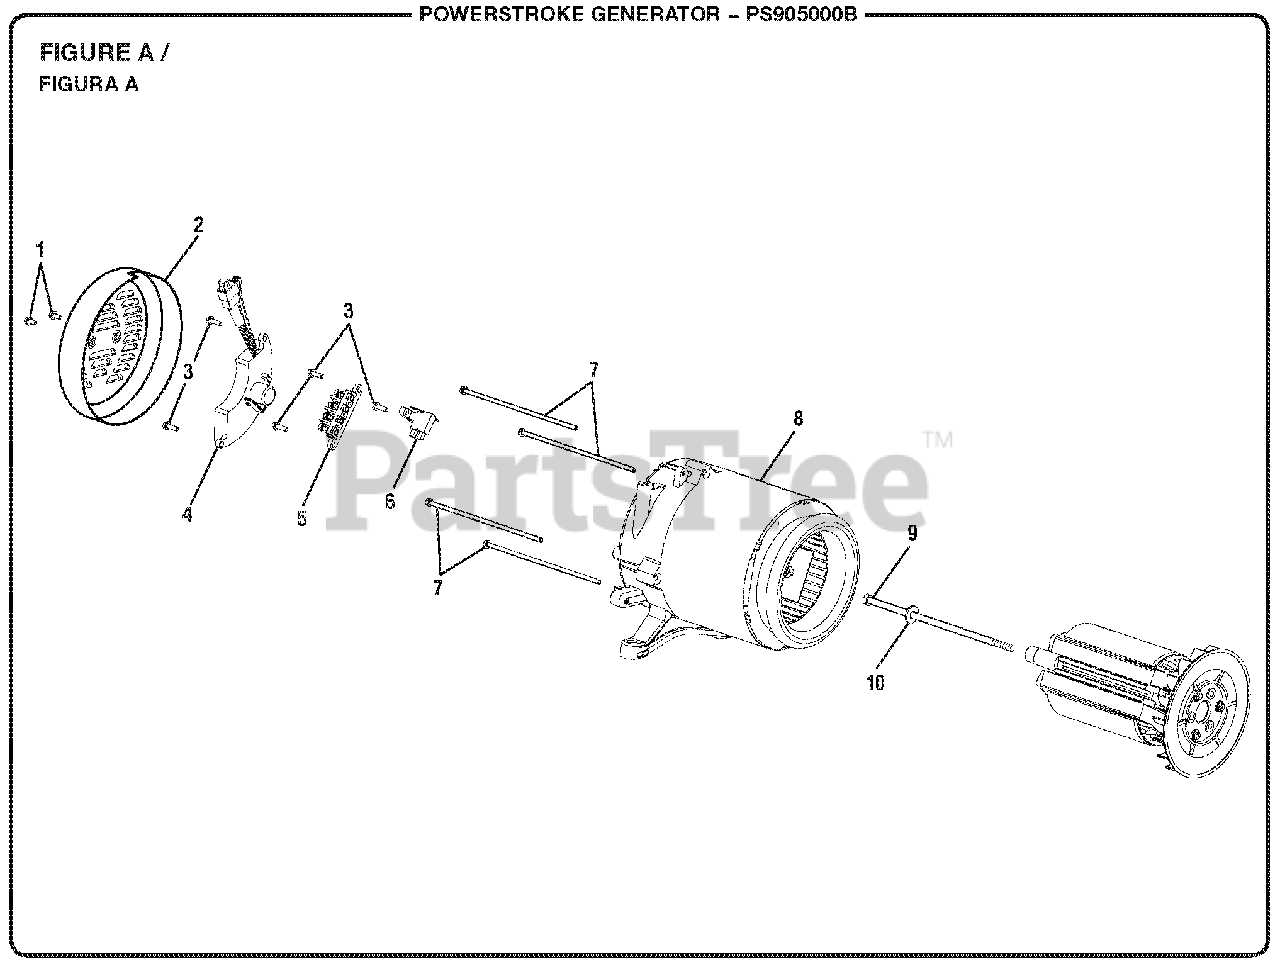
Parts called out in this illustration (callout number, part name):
1	Bolt (M5 x 12 mm, Hex Hd.)
2	Brush Cover
3	Bolt (M5 x 16 mm, Hex Hd.)
4	Automatic Voltage Regulator (5000 Watt)
5	Terminal Block Assembly
6	Brush Assembly Kit
7	Bolt (1/4-20 x 7 in., Hex Hd.)
8	Bearing Support
9	Bolt (Rotor)
10	Washer (5/16 in.)
